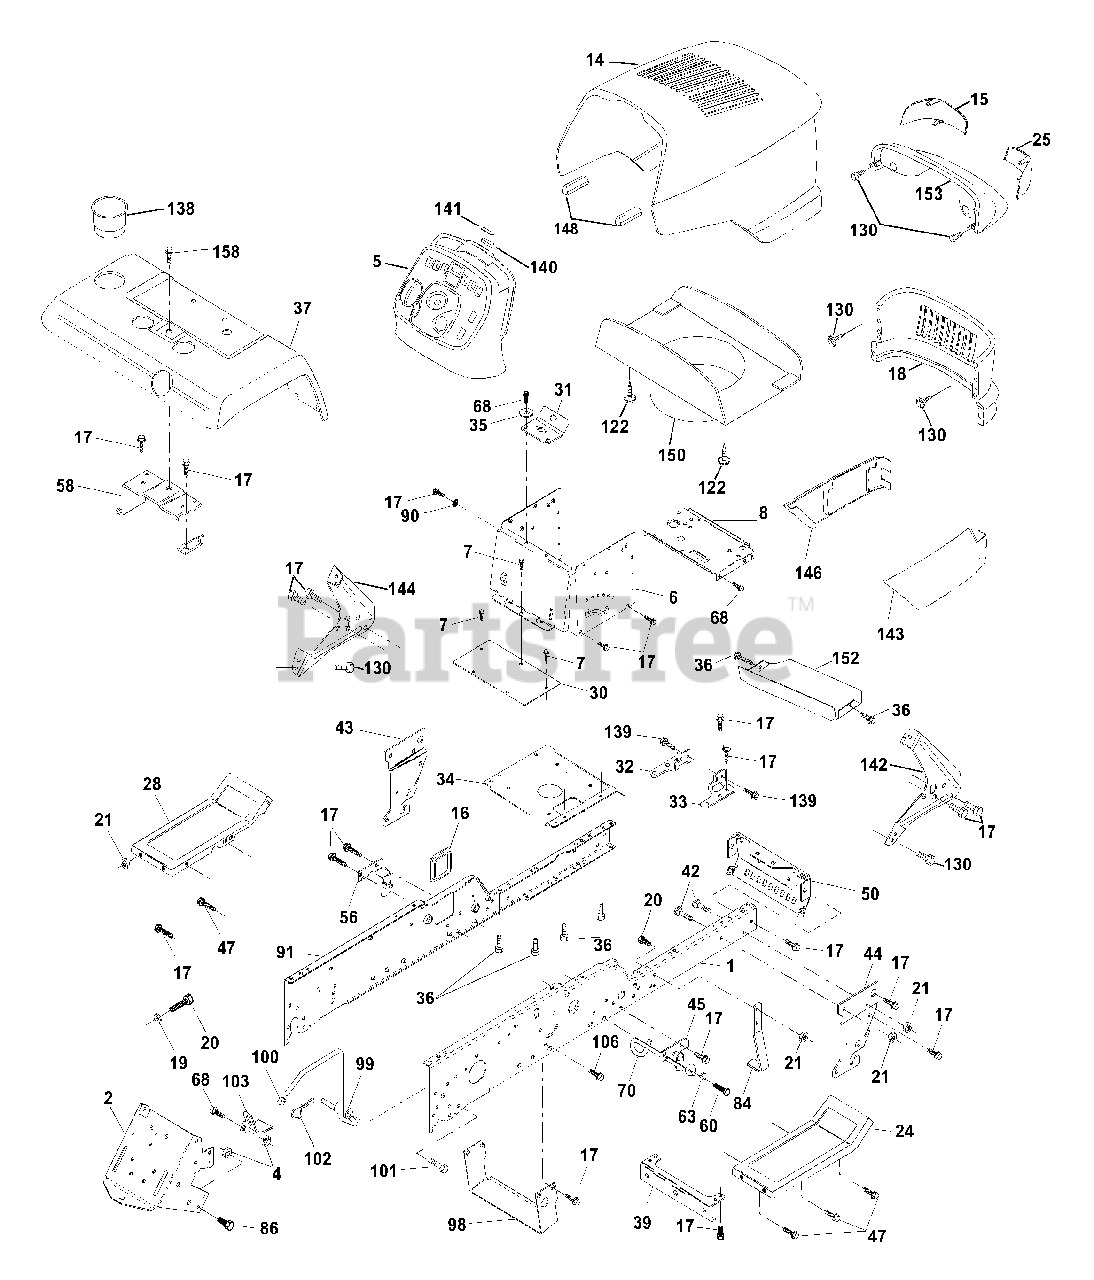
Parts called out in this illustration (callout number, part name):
1	Rail, Frame RH
2	Drawbar, Gt
4	Nut, Lock Hex 7/16 Unc
5	Dash, Plastic
6	Dash, 1PCS, Lower
7	Screw, Thd Cut 1/4-20 x 1/2
8	Support, Battery
14	Hood Asm., Pnt
15	Lens, LH Stealth
16	Cover, Access
17	Screw, 3/8-16 x 3/4
18	Grille
19	Washer 13/32 x 13/16 x 12 Ga.
20	Bolt, Fin Hex 3/8-16 x 1
21	Nut, Crownlock 3/8-16
24	Footrest, RH
25	Lens, RH Stealth
28	Footrest, LH
31	Bracket Supt 1-pc Vgt Steering
32	Bracket, Frame Pivot Lh
33	Bracket, Frame Pivot Rh
34	Plate Asm Engine Chassis
35	Washer 11/32 x 11/16 x 16 Ga.
36	Screw 5/16-18 x 3/4
37	Fender, Pnt.
39	Bracket, Axle Front
42	Bolt Rdhd Sqnk 3/8-16 Unc x 1
43	Bracket, Spnsn Front Lh
44	Bracket, Spnsn Front Rh
45	Bracket Asm., Susp Chassis Rh
47	Screw Thdrol 3/8-16 x 1/2
50	Bracket, Chassis Front
56	Bracket Asm., Susp Chassis Lh
58	Bracket Asm., Fender
60	Screw 3/8-16 x 1-1/4
63	Washer 13/32 x 1 x 14 Ga.
68	Screw, 5/16-18 x 1/2
70	Belt Keeper VGT GD
84	Stop, Over Center Mower
86	Bolt, Fin Hex 7/16-14 Unc x 1
90	Washer, Lock External Tooth 3/8
91	Rail, Frame Lh
98	Bracket Chassis Skid
99	Rod Asm. Bypass
100	Cap By Pass Rod
101	Screw Thdrol. 3/8-16 x 1-3/4
102	Retainer Spring 1"
103	Bracket Lock Bypass
106	Screw Thdrol Hex Head Zinc
122	Screw Hex WSHD 8-18 x 7/8
130	Screw Hw Hd Hi-Lo #13-16 x 3/4
138	Cupholder
139	Bolt Shoulder 5/16-18
140	Magnet Stealth
141	Striker Plate
142	Bracket Dash Stealth RH
143	Skirt Grille RH
144	Bracket Dash Stealth LH
146	Skirt Grille LH
148	Extrusion Bumper
150	Duct Heat Hood
152	Shield Browning
153	Lens, Headlight Bar
